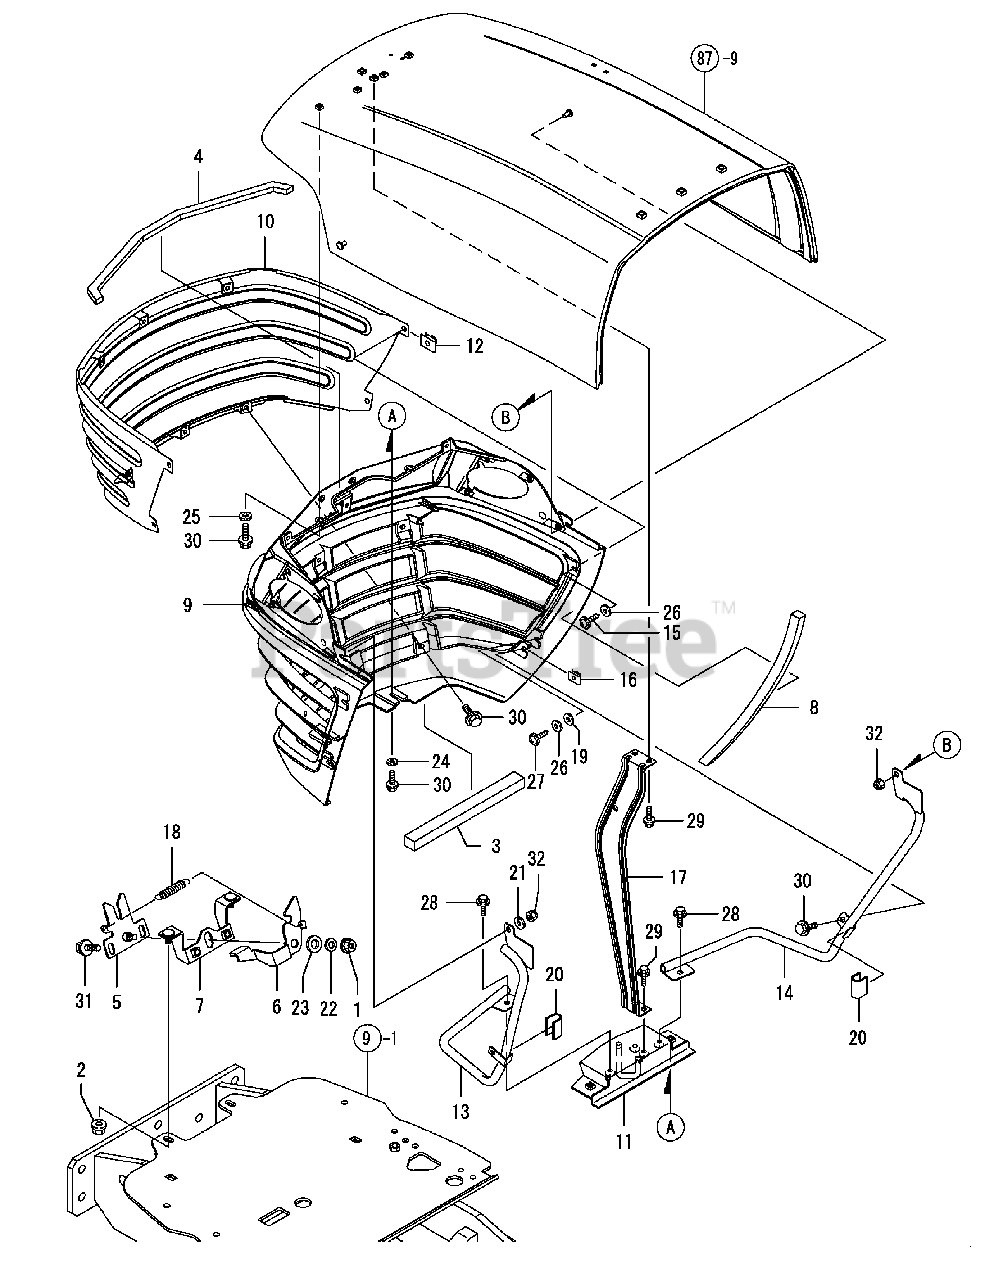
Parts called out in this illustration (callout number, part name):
1	NUT W/WASHER 8
2	NUT W/WASHER 8
3	SEAL, FRONT BRACKET
4	URETHANE, GRILLE
6	LEVER, GRILLE LOCK
7	PLATE, BASE LOCK
8	SEAL, GRILLE SIDE
10	NET ASSY, GRILLE
11	STAY ASSY, LOCK
13	FRAME ASSY, L GRILLE
14	FRAME ASSY, R GRILLE
15	SCREW 5X16
17	STAY, FRONT GRILLE
21	WASHER 6, POLISHED
22	WASHER 8, POLISHED
23	WASHER 12,POLISHED
27	SCREW, 5.0 X 20
28	BOLT M 6X 12 PLATED
29	BOLT M 6X 12 PLATED
30	BOLT M 6X 16 PLATED
31	BOLT M 8X 12 PLATED
32	U-NUT M 6 PLATED
